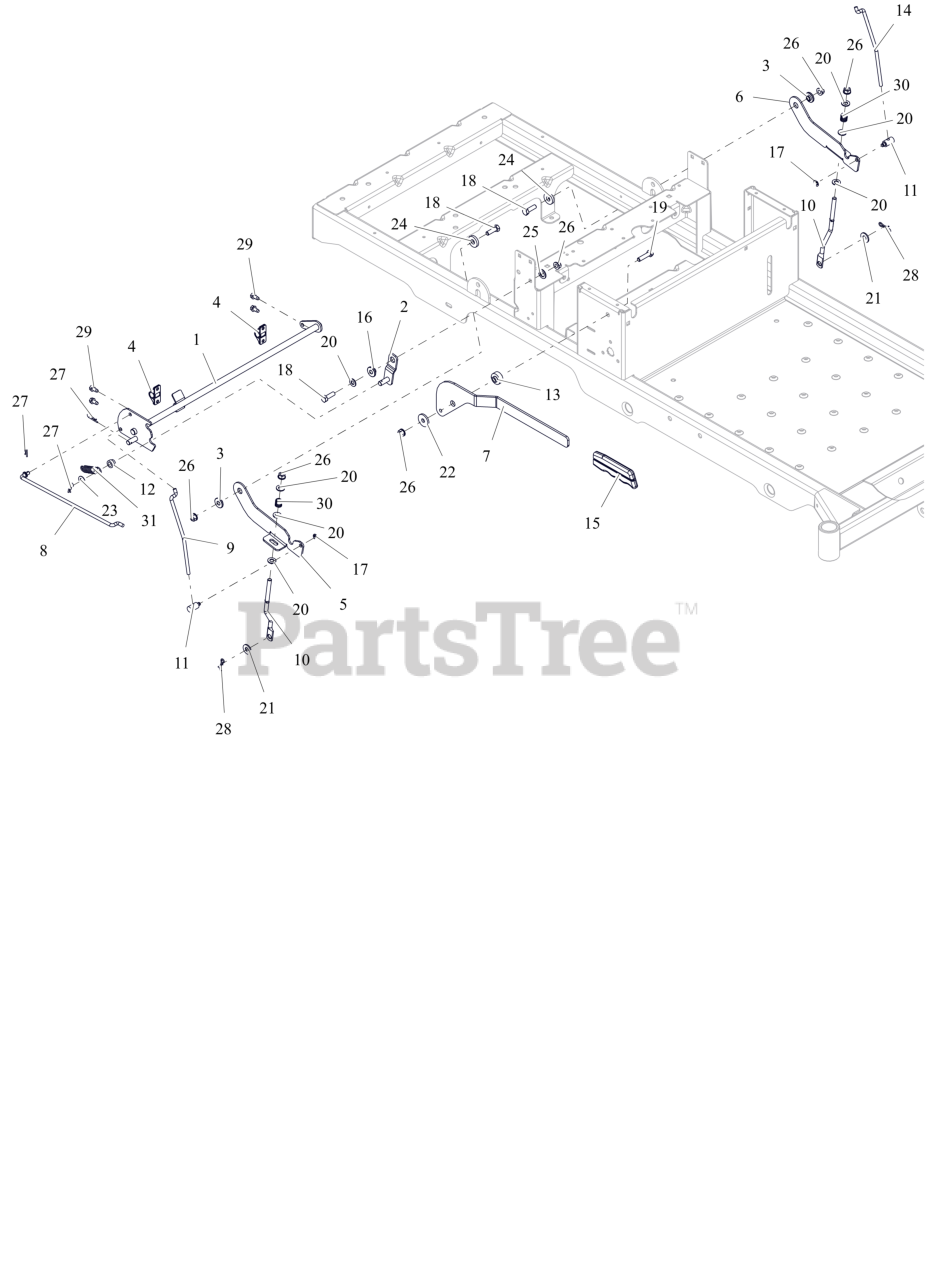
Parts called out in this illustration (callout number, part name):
1	WELDMENT, BRAKE SHAFT
2	WELDMENT,DETENT ARM
3	BSHG, FLG .325X.499X.26X.88
4	BUSHING-.50 CLAMP BLOCK MOLDED
5	LATCH,RH NETURAL
6	LATCH,LH NETURAL
7	HANDLE, PARKING BRAKE
8	LINK, BRAKE HANDLE
9	LINK, NEUTRAL RH
10	LINK, BRAKE COG
11	TRUNION, 1/4-20
13	SPCR,BRAKE .32X.49X.192X1.00
14	LINK, NEUTRAL LH
15	GRIP, PARKING BRAKE (YELLOW)
16	BSHG-FLG .32X.500X.344X.880
17	RG-RTNG-EXT .250X.025
18	BLT,HEX .31-18X1.00 G5 ZCC
19	BLT, HEX .31-18X1.25 G5 ZCC
20	WSHR,FLT .344X.688X.065 ZCC
21	WSHR,FLT .375X.875X.083 ZCC
22	WSHR, FLT .340X1.125X.135 ZCC
23	WSHR, FLT .385X.745X.030 ZCC
24	WSHR, FLT .406X1.00X.188 ZCC
25	WSHR, FLT .520X.827X.062 ZCC
26	NUT,LK-CTR-FLG .31-18 GF ZCC
27	PIN, HAIR #213 .08X1.19 ZCC
28	PIN, BOWTIE #72 ZCC
29	SCR-TAP .25-20X.50 HWH ZCC
30	SPRING, COMPRESSION
31	SG-TENS .072X.565X1.87
